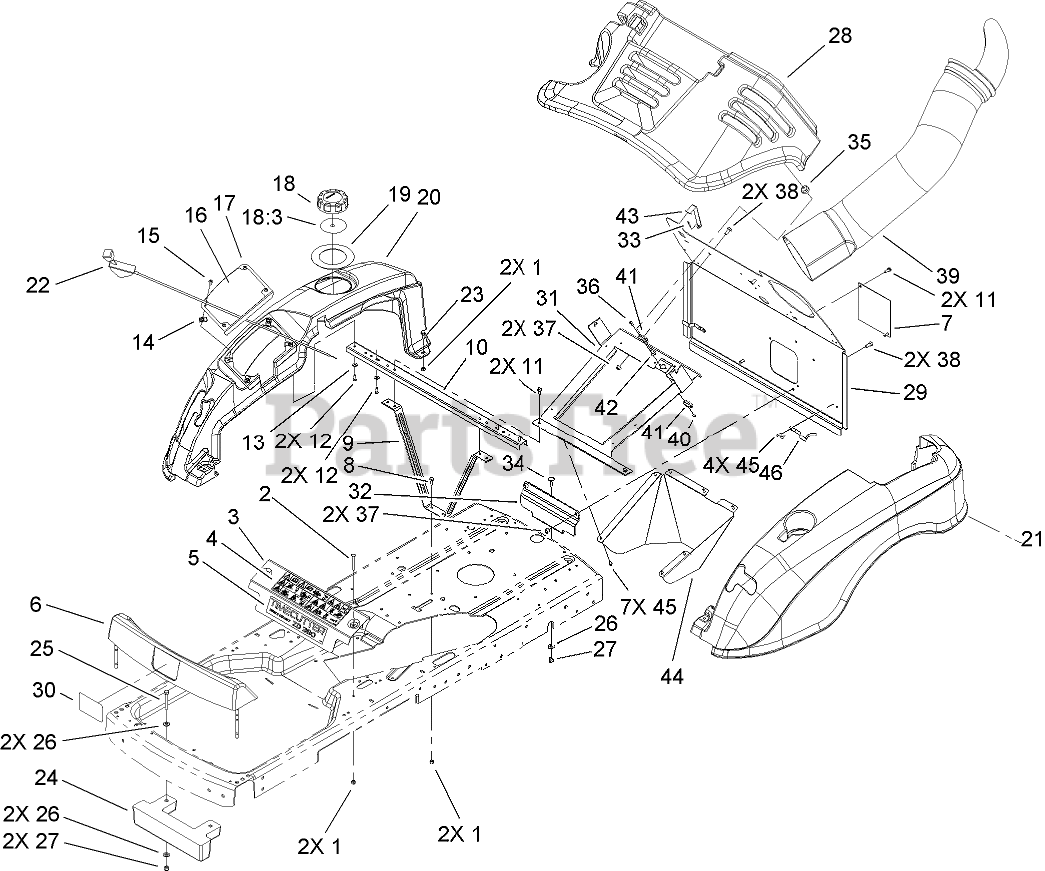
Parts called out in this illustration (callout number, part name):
1	NUT-LOCK, NI
2	SCREW-CARR
3	BRACKET-SUPPORT, FRONT
4	DECAL-DANGER
6	FOOTREST ASM
7	DOOR-PLUG ACCESS
8	SCREW-HH
9	BRACE ASM
10	CHANNEL-CROSS
11	SCREW-HWH, THREAD ROLL
12	SCREW-PLASTITE
13	WASHER-FLAT
15	SCREW-PRH
16	DECAL-CONTROL
17	PANEL-CONTROL
18	GAS CAP ASM
18:3	GASKET-CAP, GAS
19	SEAL-RUBBER
20	COVER-SIDE, RH
21	COVER-SIDE, LH
22	CABLE-THROTTLE
23	SCREW-SHOULDER
24	WEIGHT-BAGGER
25	SCREW-HH
26	WASHER-FLAT
27	NUT-LOCK, NI
28	COVER-ENGINE
29	SHIELD-HEAT, BAG
31	HINGE-OFFSET
32	BRACKET-HITCH
33	PIN-COTTER
34	SCREW-CARR
35	GROMMET
36	SCREW-HSBH
37	NUT-LOCK, NI
38	SCREW-HH
39	TUBE-DISCHARGE
40	NUT-LOCK, NI
42	PIN-HOOD
43	TAB-SWITCH
44	DUCT - ENGINE
45	SCREW-TAPTITE
46	CLIP - RETAINER
